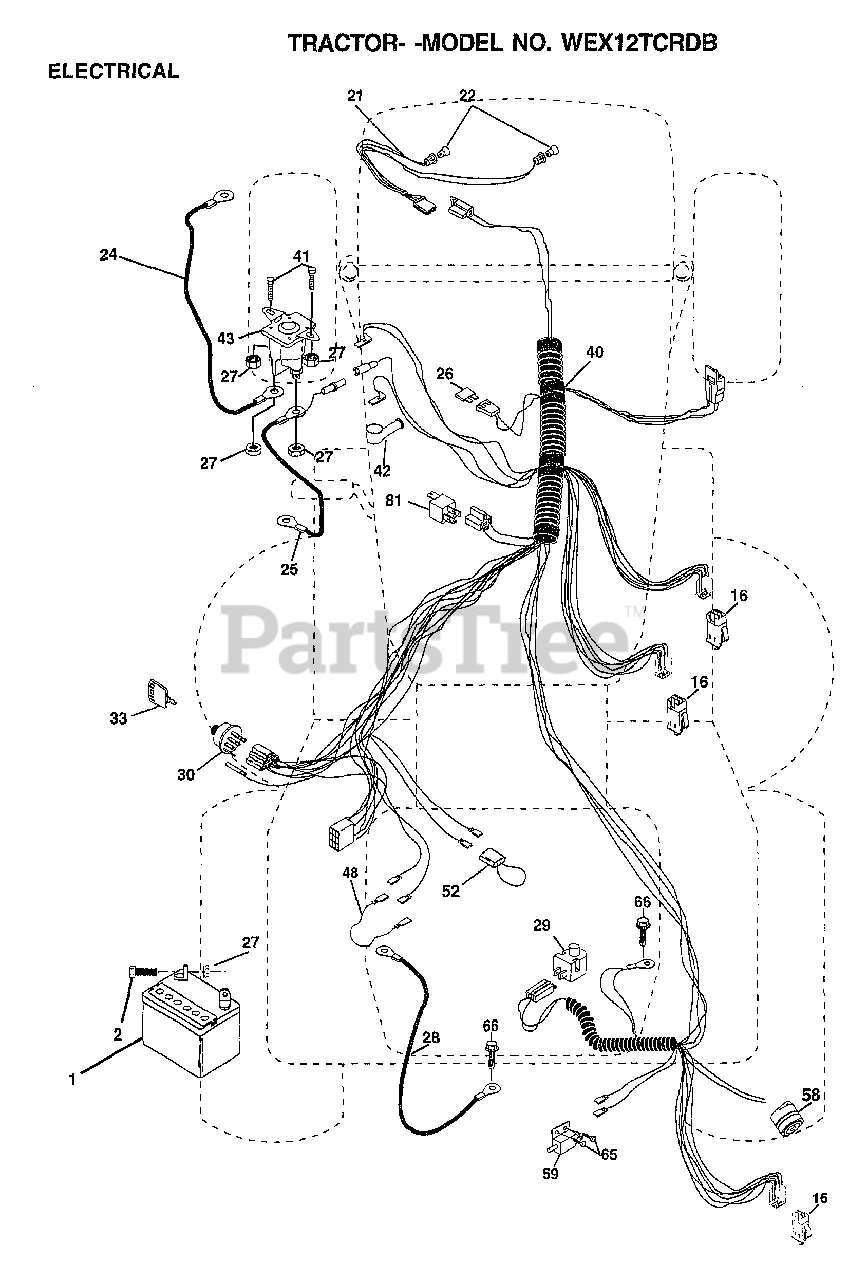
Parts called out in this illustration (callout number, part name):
2	BOLT LT
16	SWITCH INTERLOCK
21	HARNESS.ASM.LIGHT W/4152J
22	HEADLAMP BULB
24	CABLE ASM.
25	CABLE.BATTERY.CRD
26	FUSE.15 AMP
27	NUT
28	"CABLE.GRD.6GA/18""BLACK"
29	SWITCH.PLUNGER
30	SWITCH.IGN.
33	KEY MLD GEN DELTA
40	HARNESS IGN CORD
41	BOLT HXHD FIN
48	ADAPTER AMMETER
52	PROTECTION LOOP
58	BUZZER CRD
59	SWITCH.FBI.CRD
65	SCREW
66	SCREW LT
81	RELAY ASSY T
